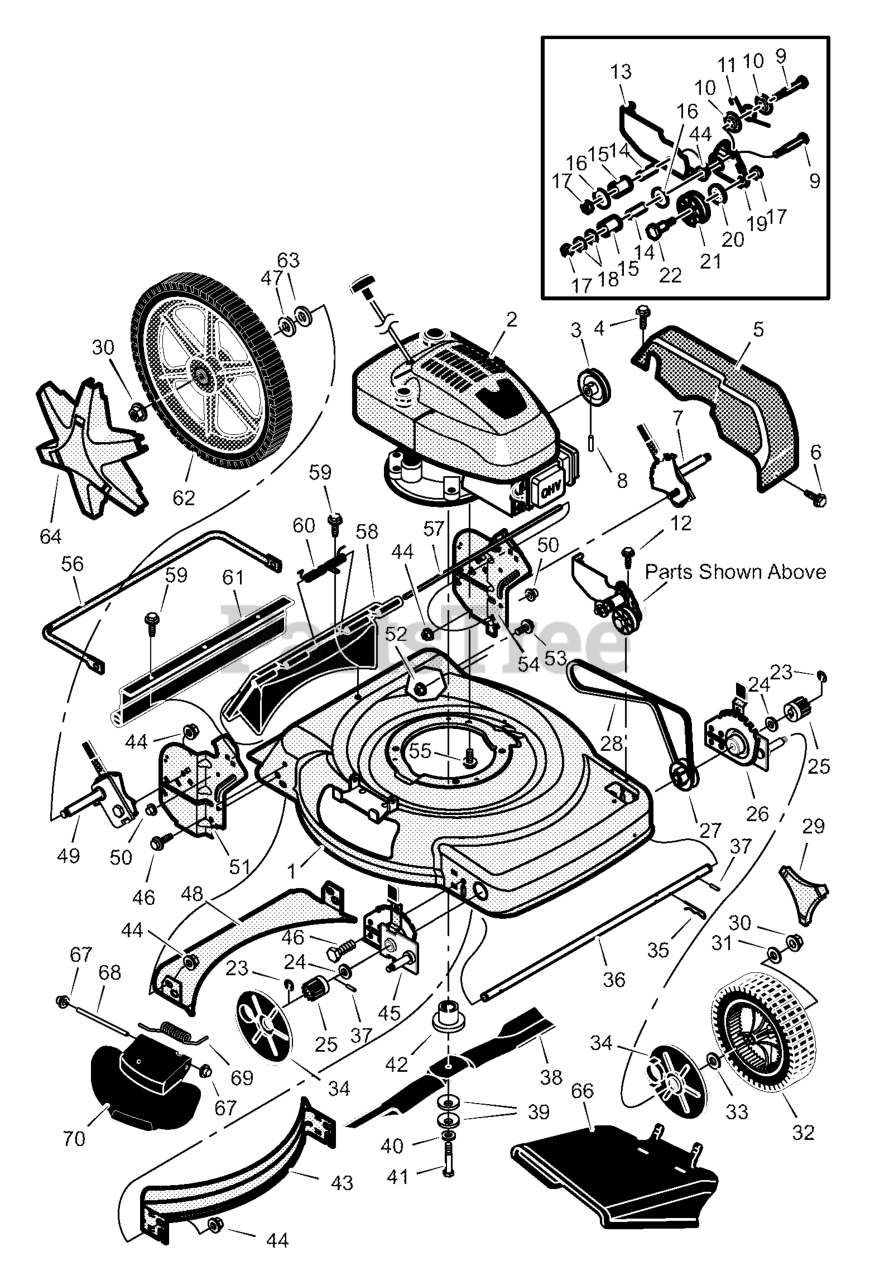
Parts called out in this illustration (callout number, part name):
1	Housing
2	Engine
3	Pulley, Drive
5	Cover, Belt (Gray)
7	Adjuster, Left Rear Height
8	Pin, Spring
10	Spacer, Idler Arm
12	Screw
13	Bracket, Idler Support
14	Bearing, Idler
15	Pulley, Idler
17	Nut
18	Washer
19	Arm, Pivot
20	Spacer, Idler
21	Pulley, Idler
22	Bolt, Shoulder
25	Gear, Pinion
26	Adjuster, Left Front Height
27	Pulley, Axle
29	Cap, Hub
30	Nut, Flange
31	Washer
32	Wheel & Tire, Front
34	Cover, Dust
35	Pin, Hair
37	Pin, Drive
39	Washer, Belleville
42	Adapter, Blade
43	Baffle, Front
44	Nut, Flange
45	Adjuster, Right Front Height
46	Bolt
48	Baffle, Rear
49	Adjuster, Right Rear Height
50	Push On Cap
51	Bracket, Left Handle
52	Nut, Flange
53	Bolt
54	Bracket, Left Handle
55	Bolt, Engine
57	Rod, Pivot
58	Door, Rear (Gray)
61	Guard, Rear
62	Wheel & Tire, Rear
64	Cap, Hub
66	Deflector, Chute
67	Push On Cap
68	Rod, Pivot
69	Spring, Torsion
70	Cover, Mulch (Gray)
